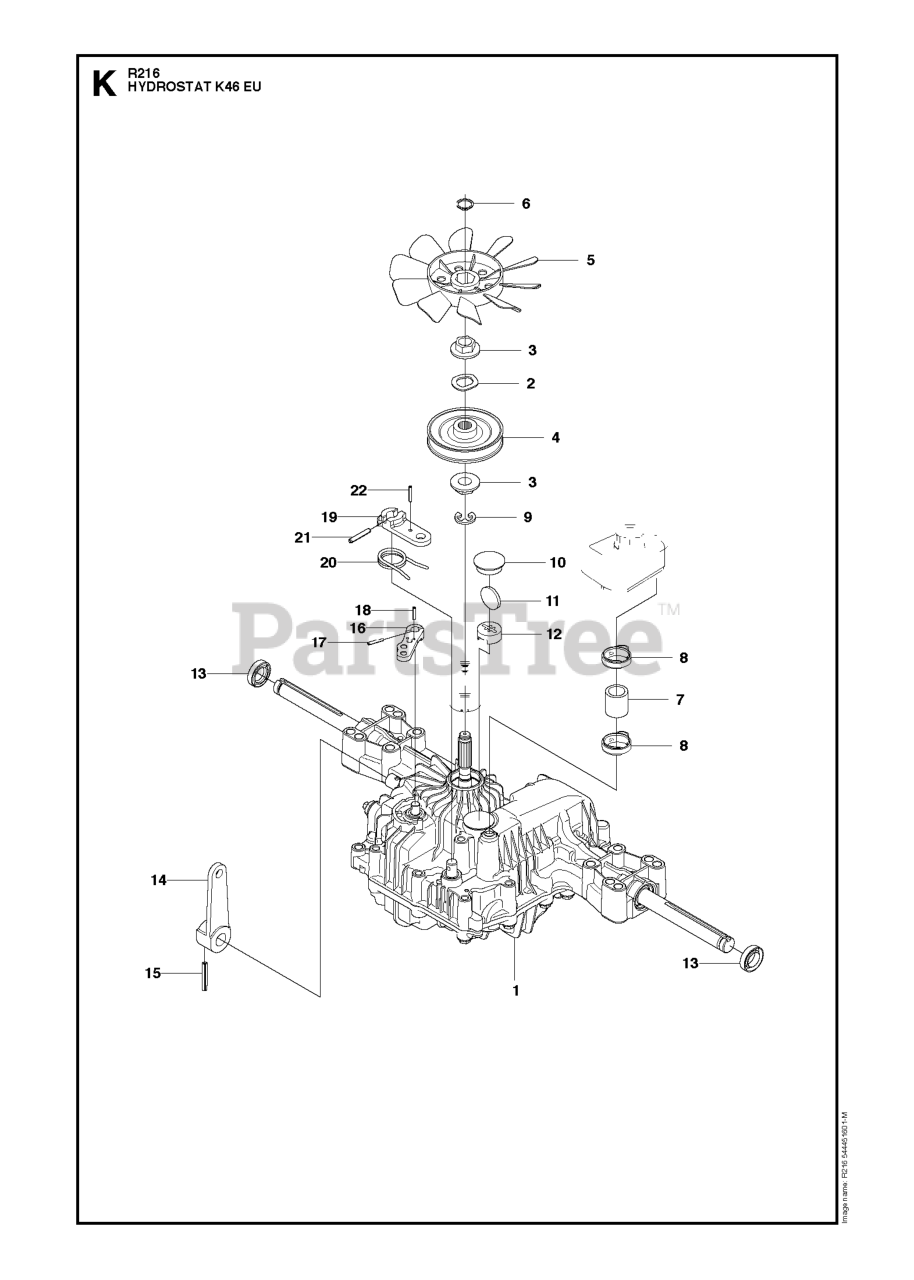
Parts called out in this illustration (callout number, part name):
1	HYDROSTAT 7A646024070
5	FAN.BLACK.1A646083070
6	RETAINING RING **
8	CLAMP
12	MAGNET HOLDER
13	RP SEAL.19, 19216334280
14	CONTROL LEVER
20	RETURN SPRING
